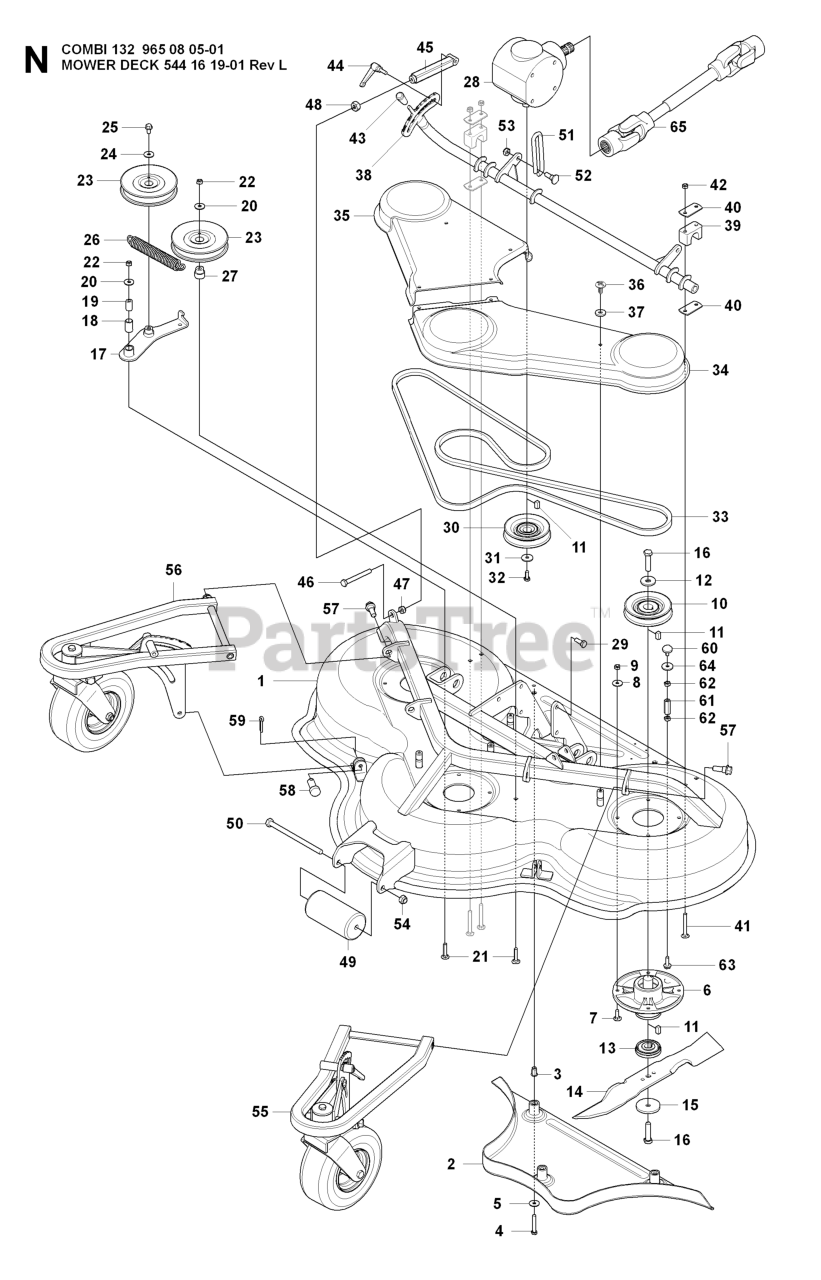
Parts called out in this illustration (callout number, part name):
3	BLIND RIVET NUT
5	WASHER BRB 8.4X17
8	WASHER BRB 8.4X17
9	LOCKNUT M8
10	PULLEY SPB DP112 COMPLETE
14	BLADE REAR DISCHARGE/MULCH C13
17	BELT TENSIONER CUTTING DECK
21	Screw Mvbf 8 X 40
22	LOCKNUT M8
25	BOLT FLANGE - M8X16
26	DRAW SPRING L=122
28	BEVEL GEAR
29	Screw M10x25
30	PULLEY SPB DP112
32	SCREW 8X20
35	BELT COVER C132 R
39	BEARING COVER
42	LOCKNUT M8
44	TURNING KNOB M 8
45	PARALLEL ROD C 132
48	NUT
49	ROLLER
52	SCREW LINK
53	NUT
55	WHEEL SUSPENSION LEFT
56	WHEEL SUSPENSION RIGHT
60	ANTIVIBRATION ELEMENT
62	NUT
